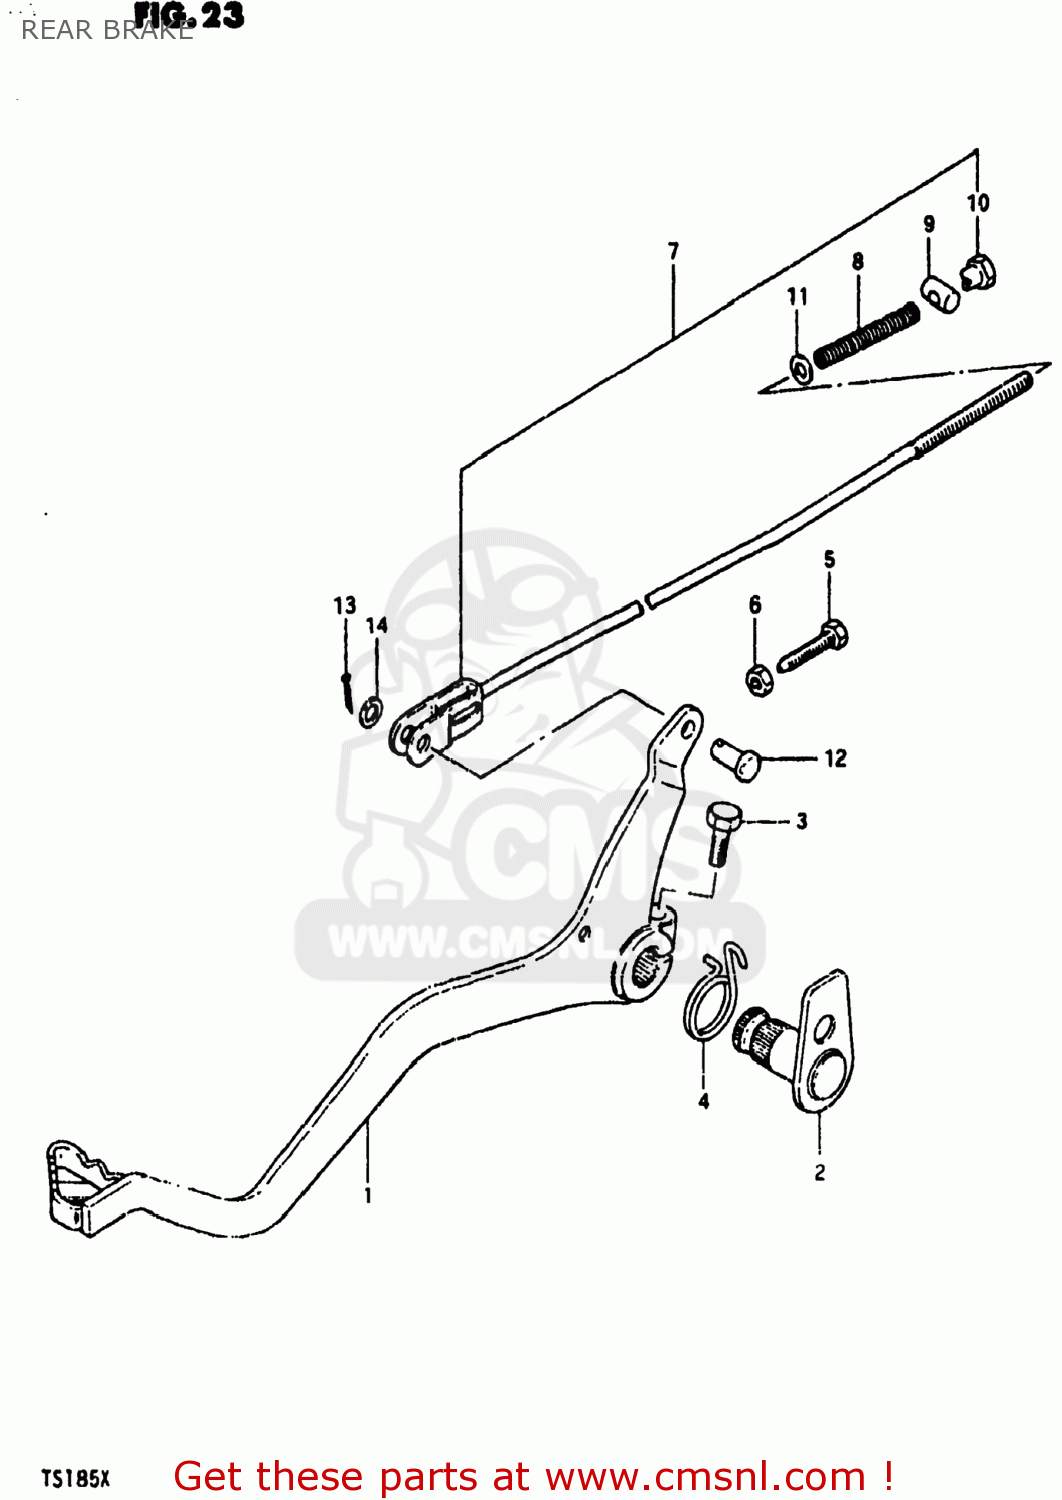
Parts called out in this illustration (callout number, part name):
1	PEDAL,BRAKE
2	ARM,BRAKE PEDAL
3	BOLT
4	SPRING
5	BOLT(6X23)
6	NUT
7	ROD ASSY,RR BRAKE
8	SPRING
9	PIN
10	NUT
11	WASHER
12	PIN(L:13.5)
13	PIN 20X20
14	WASHER
